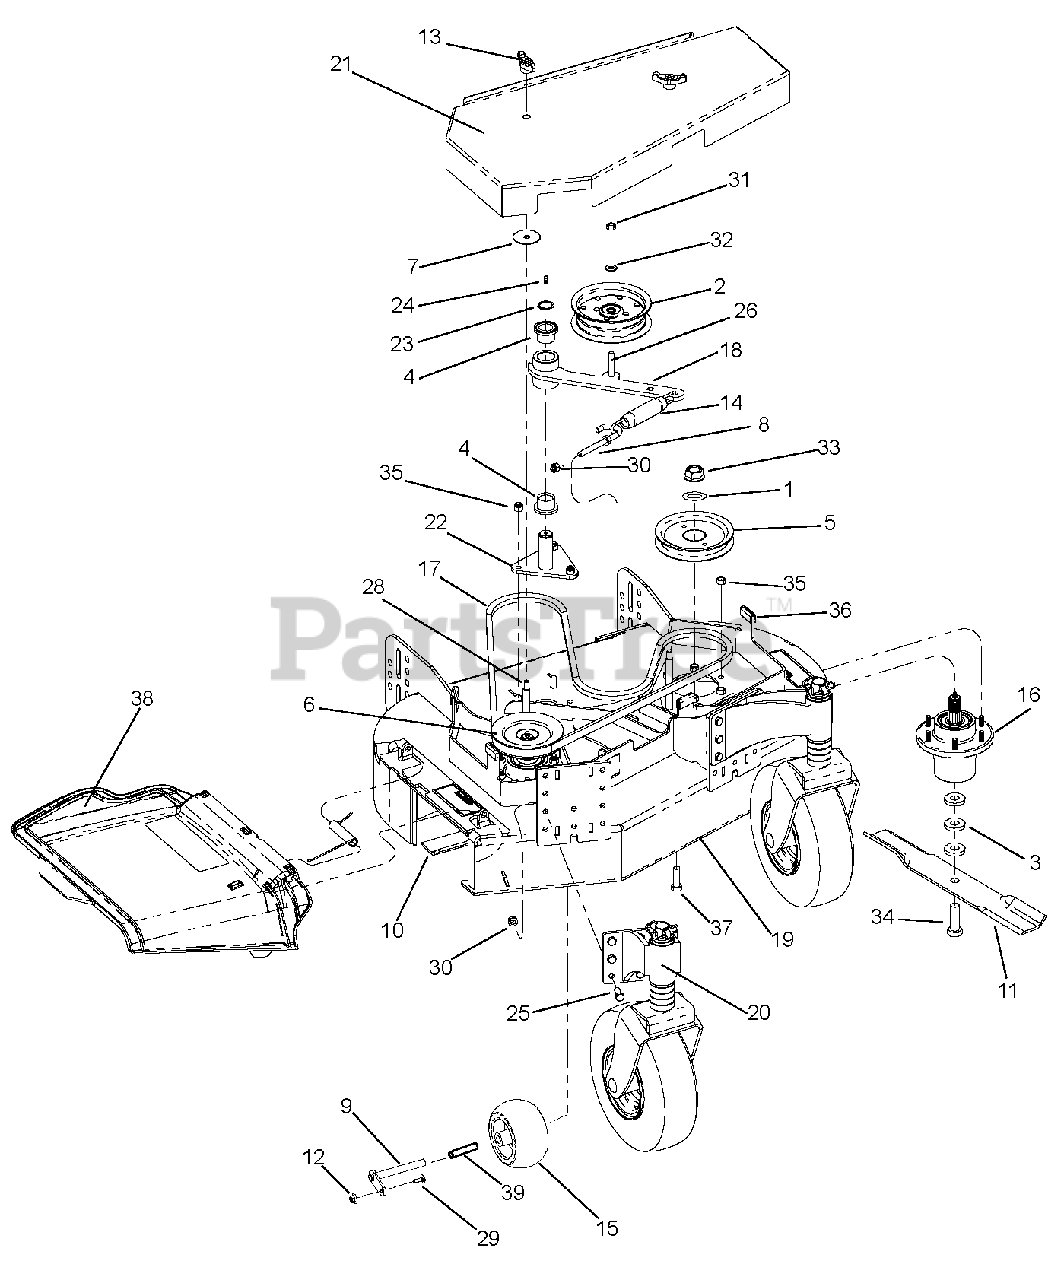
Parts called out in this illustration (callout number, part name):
1	Washer, .75 x 1.3125 x .120
2	Pulley, Flat 5.0 x .38 w/Bearing
3	Washer, Blade
4	Bearing, Flg 1.00 x 1.25 x 1.00
5	Pulley, Spline Spindle Offset
6	Pulley, V-belt 5.27 x .990 w/Spl
7	Washer, .402 x 2.00 x .055 Fend Y
8	J-bolt, 3/8-16 x 4.00 Y
9	Pivot, Retainer Weld
10	Blade, 16.50 Lo-Lift
11	Blade, 18"
12	Nut, 1/4" Flange
13	Knob, Locking
14	Spring, Tension
15	Wheel, Gage
16	Assembly, Spindle Housing
17	Belt, HB 80.3 El AMD OHR
18	Weldment, Idler Arm
19	Weldment, 34" Deck w/Decals
20	Assembly, Front Wheel Caster (see page 20 for parts)
21	Shield, Deck 34 w/Decals
22	Weldment, Idler Pivot
23	Snap Ring, 1.00 x .042 Ext
24	Grease Zerk, 1/4-28 Straight .69 LG
25	Bolt, Hex .38-16 x 1.0
26	Bolt, 3/8-16 x 2.25 Hex Grade 5 Y
27	Nut, Hex .38-16 Grade 5 Y
28	Bolt, .38-16 x 1 Grade 5 Round Head Square Neck
29	Bolt, 1/4-20 x .750 Round Head Square Neck Grade 5 Y
30	Nut, Flange .375-16
31	Nut, .38-16 Low Crown Locking Acorn
32	Washer, .406 x .813 x .065 Flat Y
33	Nut, 3/4-16 Flange Grade 8 Y
34	Bolt, 5/8-11 x 2.00 Hex Grade 8 Y
35	Nut, Locking-Nylon .38-16
36	Trim 1/4, 2" L
37	Bolt, 5/16-18 x .750 Hex 5 Y
38	Discharge Chute Assembly, (see page page 21)
39	Spacer, .510 x .625 x 3.35
